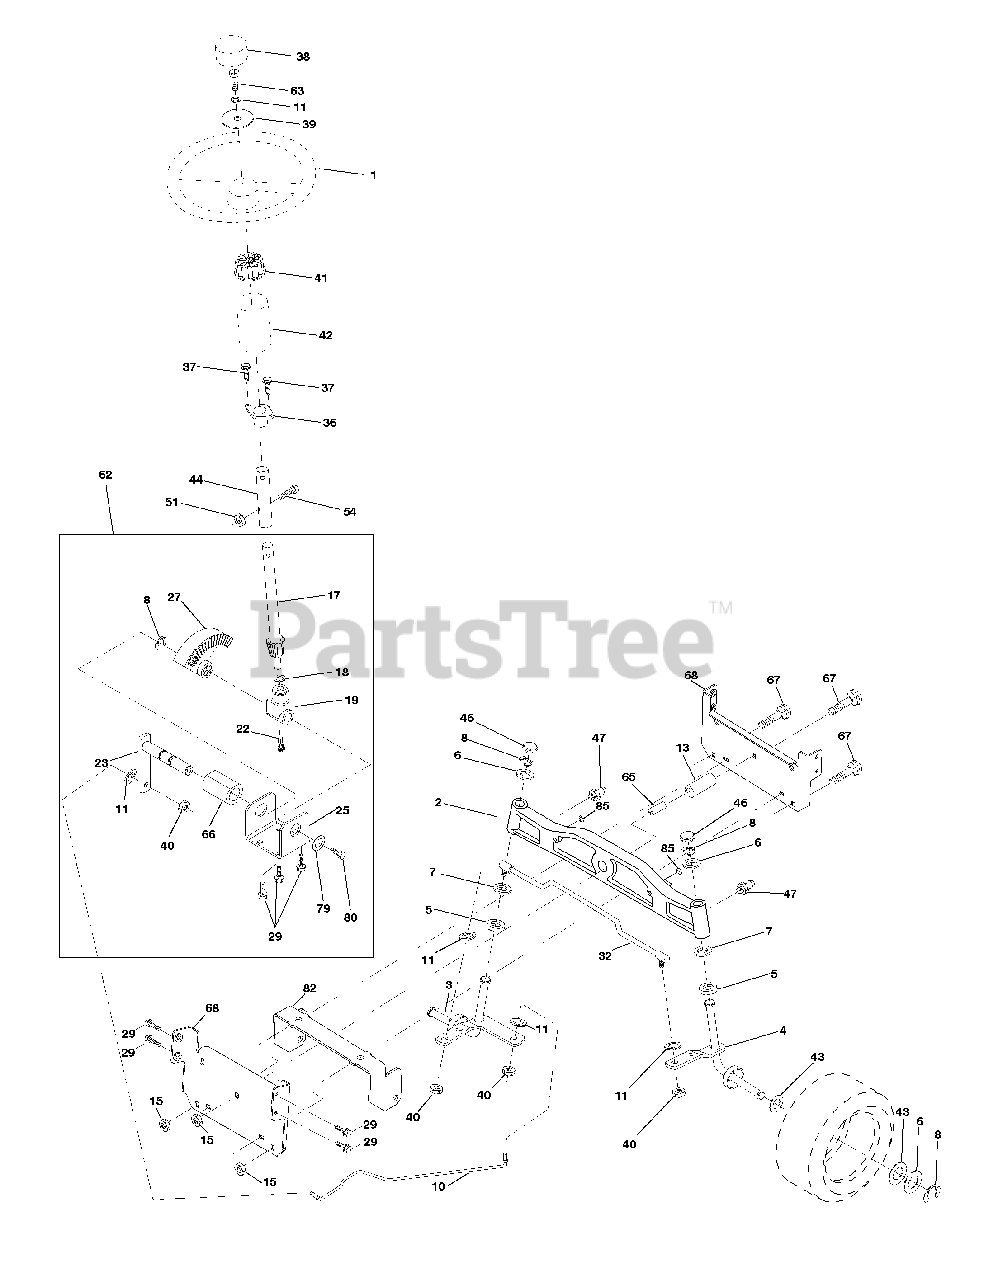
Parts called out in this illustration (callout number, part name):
1	Wheel Steering
2	Axle Cast Lt Machined
3	Spindle Asm LH
4	Spindle Asm RH
5	Bearing Race Thrust Harden
6	Washer 25/32 X 1-5/8 X 16 Ga
7	Washer 27/32 X 1-1/4 X 16 Ga
8	Ring Klip #t5304-75
10	Link Drag Extended Cast
11	Washer Lock Hvy Hlcl Spr 3/8
13	Spacer Brg Axle Front
15	Nut Hex Flange Lock Yel D
17	Shaft Asm Strg
18	Washer Thrust 515x 750x 033
19	Support Shaft
22	Screw Hex Wshhd Torx
23	Shaft Asm Pittman
25	Bracket Steering
27	Gear Sector
29	Screw 3/8-16x3/4
36	Bushing Strg
37	Screw
38	Insert Cap Strg Wh
39	Washer 13/32 x 1-1/20 x 11 Ga.
40	Lock nut
41	Adaptor Wheel Strg
42	Boot Steering
43	Washer 25/32 X 1 1/4 X 16 Ga
44	Extension Steering Non-Adjust
46	Cap Spindle Fr Top Blk
47	Fitting Grease
51	Nut Crown Lock 5/16-18
54	Bolt Fin Hex 5/16-18 Unc x 1 1/4
62	Kit, Steering Assembly Svc
63	Bolt Fin Hex 3/8-16 Unc x 1 Gr 5
65	Spacer Axle
66	Bearing Arm Pittman
67	Bolt, Rdhd Sqnk 3/8-16 x 2-1/4
68	Axle, Brace
74	Joint Asm Ball Rh
75	Joint Asm Ball Lh
76	Rod Tie Link Noram
77	Nut Hex Jam 3/8-24 Unf Lh
78	Nut Hex Jam 3/8-24 Unf
79	Washer 13/32 x 1 1/4 x 12 Ga
80	Bolt Hex Nylon 3/8-16 x 3/4
82	Bracket Susp Chassis Front 15"
